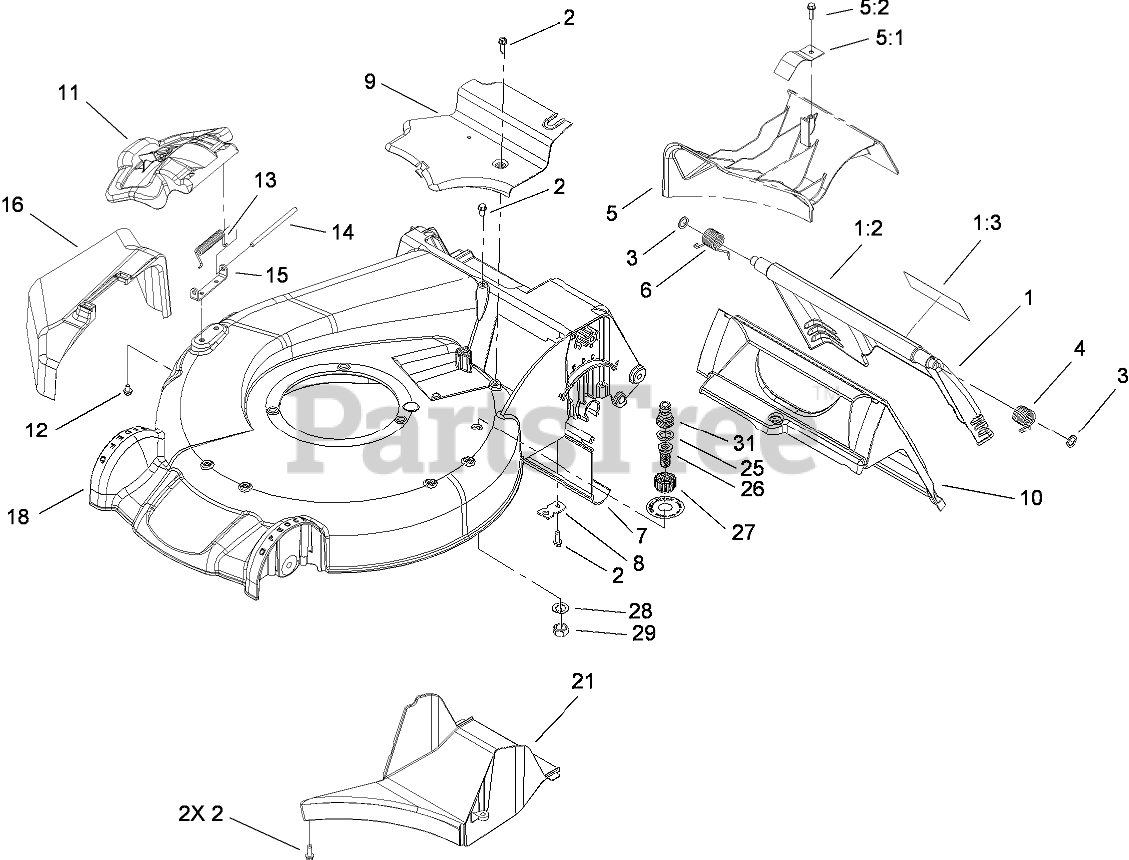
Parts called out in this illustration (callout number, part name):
1	REAR DOOR ASM
1:2	DECAL-WARNING
1:3	DECAL-WARNING
2	SCREW-HWHTF
3	WASHER-NYLON
4	SPRING-TORSION
5	PLUG-MULCH ASM
5:1	TAB-SPRING
5:2	SCREW-HWH
6	SPRING-TORSION
7	SHIELD-TRAILING
8	BRACKET-CABLE, TRACTION
9	COVER-BELT
11	DISCHARGE DOOR ASM
12	SCREW-HWH
13	SPRING-TORSION
14	ROD-COVER
15	BRACKET-COVER
16	CHUTE-DISCHARGE, SIDE
18	HOUSING ASM
21	TUNNEL-DISCHARGE
25	WASHER-SEAL, WASHOUT PORT
26	PORT-WASHOUT
27	COUPLING-HOSE, WASHOUT PORT
28	WASHER-TOOTH, INTERNAL
29	NUT-JAM
31	ADAPTER-CONNECT, QUICK
